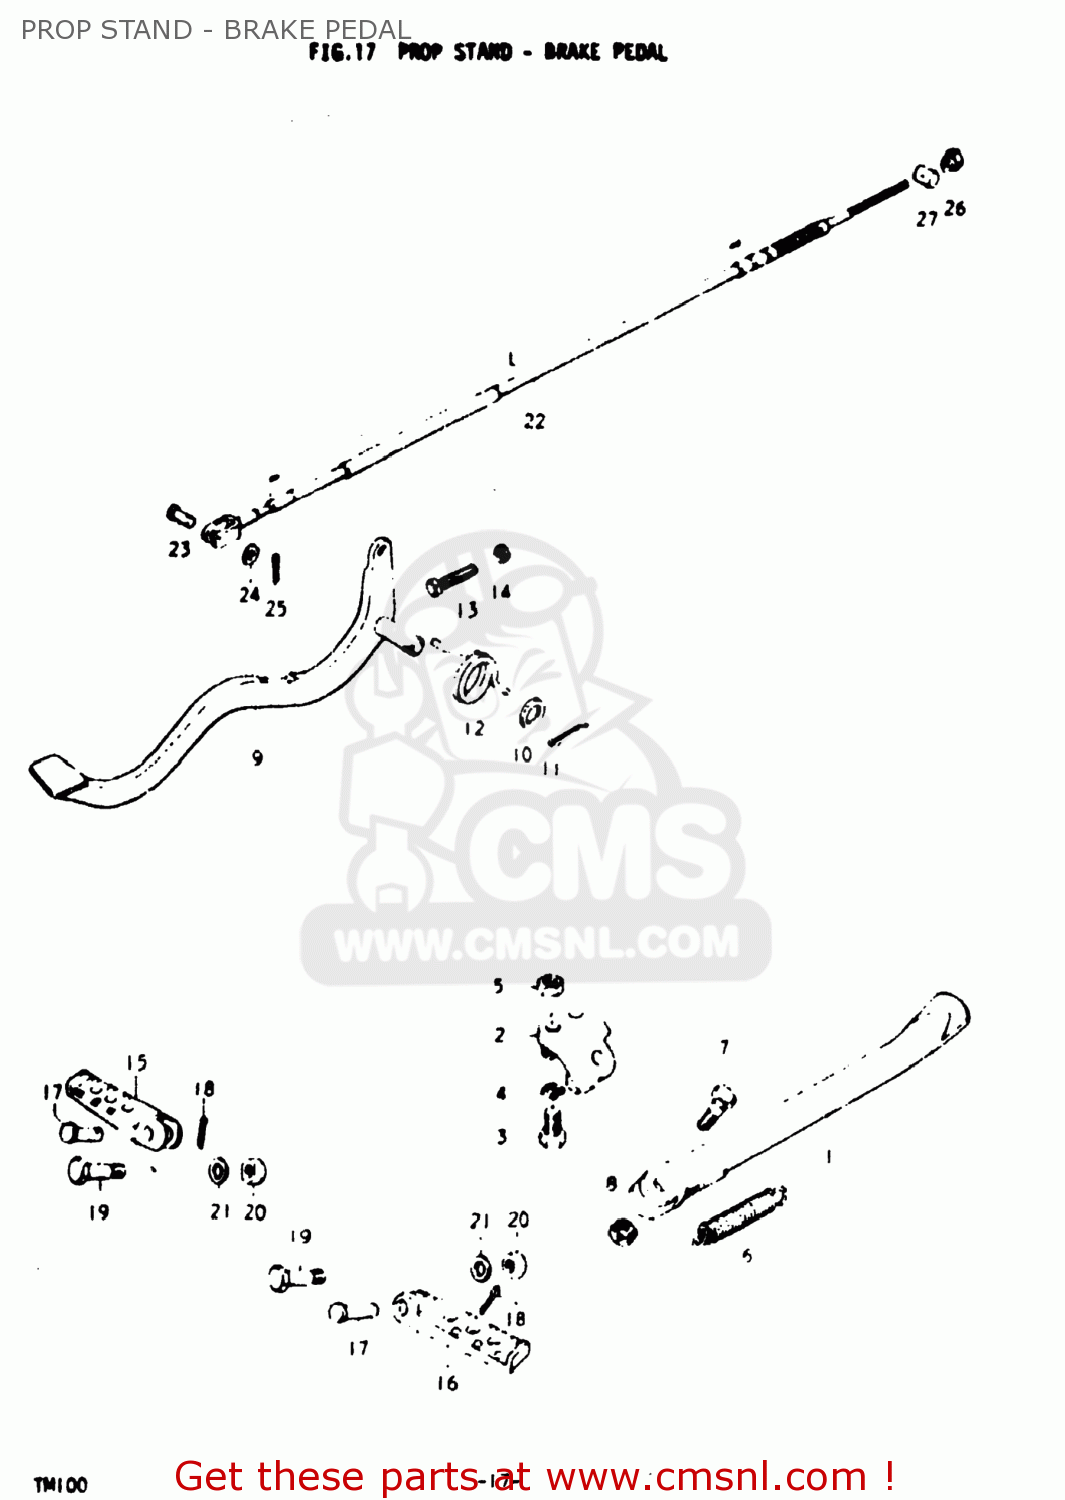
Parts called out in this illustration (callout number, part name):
1	STAND,SIDE
2	BRACKET,SIDE STAND
3	BOLT 10X25
4	LOCK WASHER
5	NUT
6	SPRING
7	BOLT(10X30)
8	NUT
9	PEDAL,BRAKE
10	WASHER
11	PIN 30X20
12	SPRING
13	BOLT
14	NUT
15	BAR,FRONT FOOTREST
16	BAR,FOOTREST,LEFT
18	PIN
19	BOLT
20	NUT
21	WASHER
22	CABLE,RR BRAKE
23	PIN(L:17.5)
24	WASHER
25	PIN
26	NUT
27	PIN(11X18)
